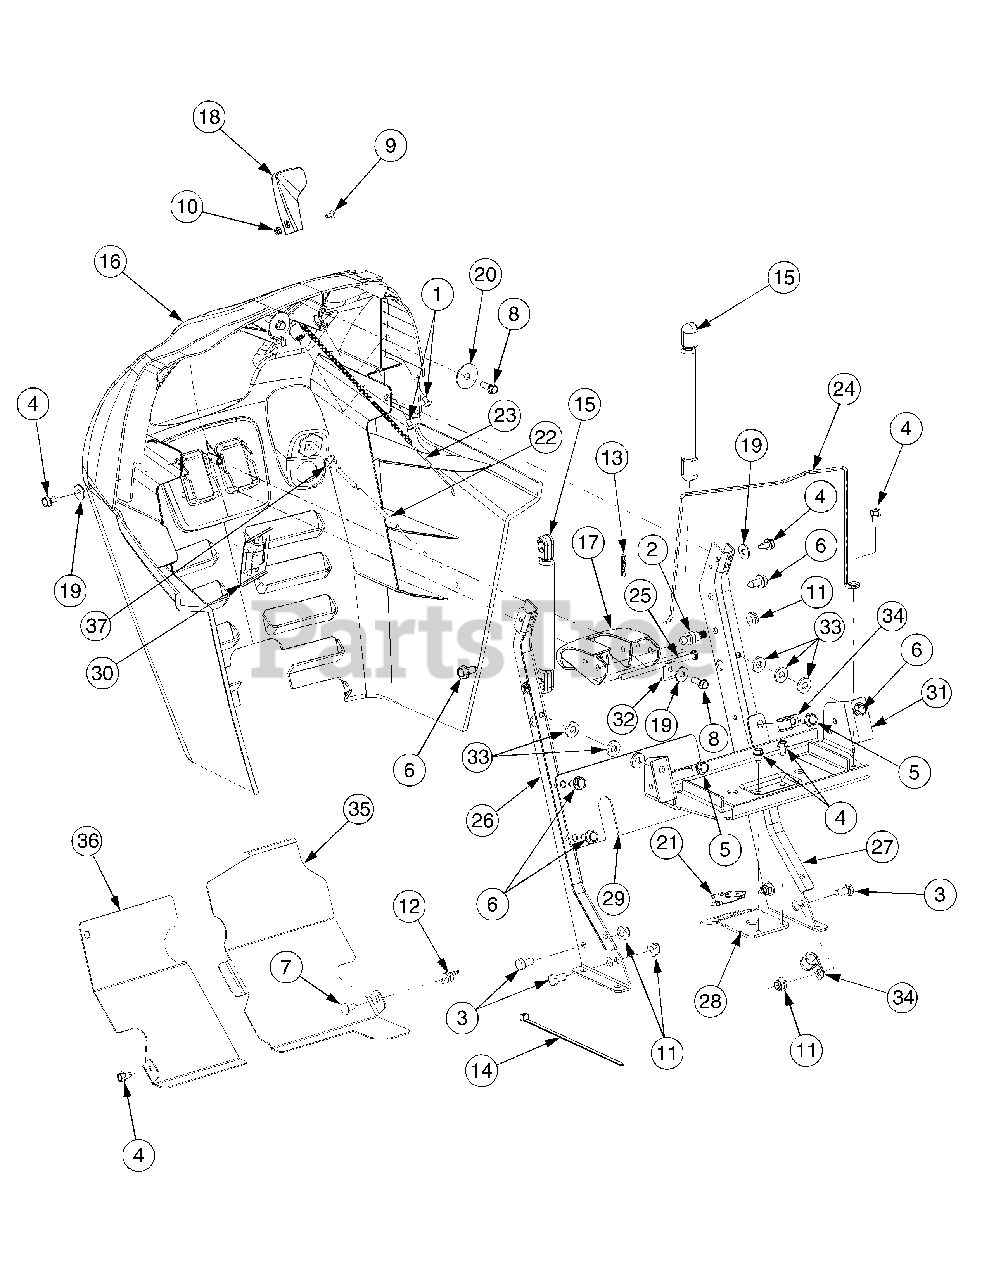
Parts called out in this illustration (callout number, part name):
1	Screw, #10-24 X .375
2	Screw, Ball Shoulder. 5/16-18 x .48
3	Screw, Hex Cap, 5/16-18 x .625 GR5
4	Screw, Self-tapping, 1/4-20, 0.500
5	Screw, Hx. Wash. Hd, Tapp. 5/16-18 x .875
6	Screw, Hx. Wash. Hd, Tapp, 5/16-12 x .75
7	Screw, Carriage, 1/4 -20 x .62
8	Screw, 1/4-15, 0.75
9	Screw, Truss Mach., #8-32 x .375
10	Nut, Hex, #8-32 GrA
11	Nut, Hx Insert Flange Lck, 5/16-18 GrF
12	Nut, Wing, 1/4-20
13	Internal Cotter Pin, .072 x 1.13
14	Tie, Cable
15	Cylinder, Gas
17	Lever, Dash, Cruise
18	Knob, Throttle Control
19	Washer, Flat, .28 x .74 x .063
20	Washer, Flat, .33 x 1.25 x .06 HT
21	Bushing, Steering Shaft
22	Cable, Choke
23	Cable, Throttle Control
25	Rod, .25 x 4.55
33	Washer, Flat, .344 x .75 x .12
34	Clamp, 9/16
37	Nut, Flange Lock, 3/8-16 Gr5
